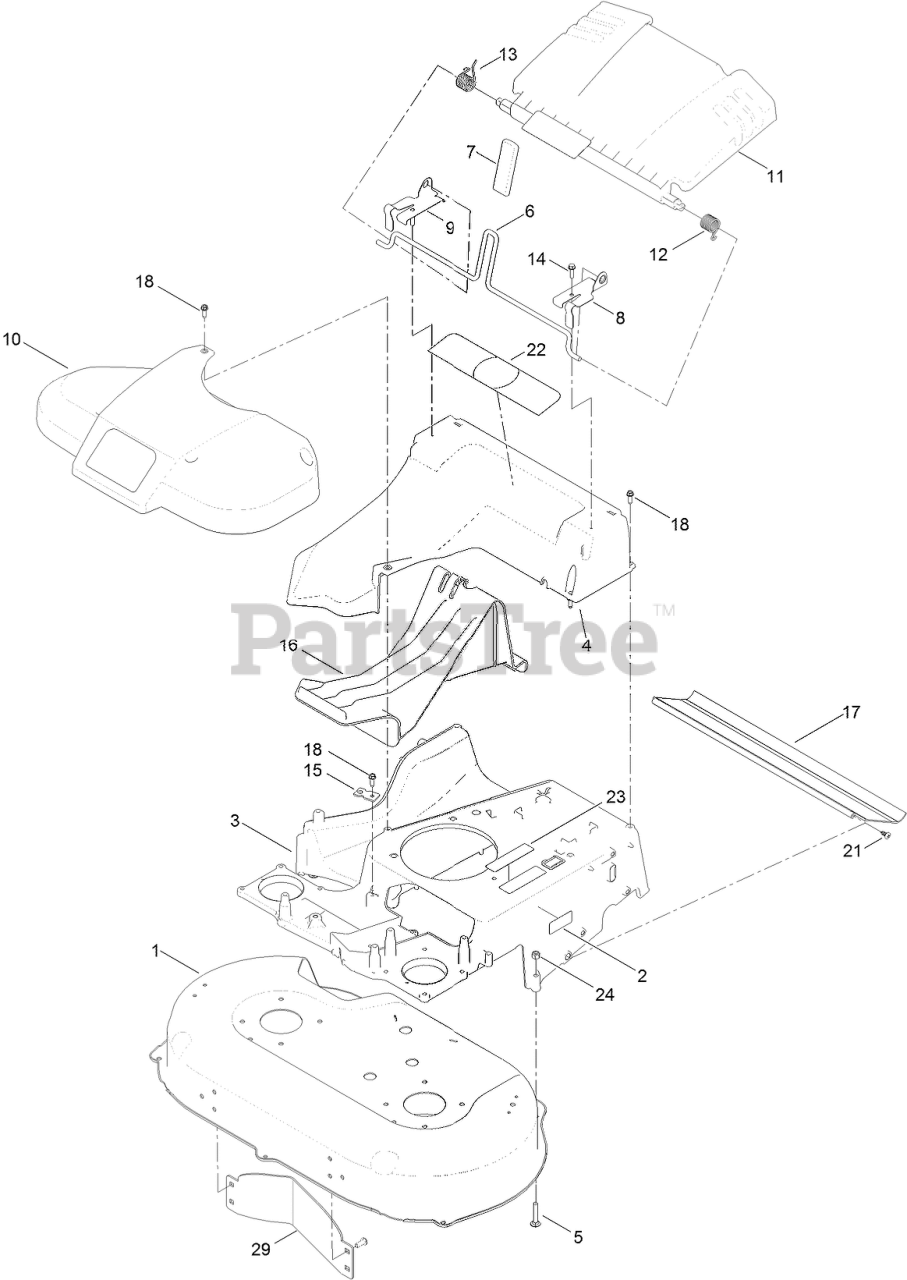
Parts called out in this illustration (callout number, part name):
1	HOUSING ASM
2	DECAL-LOCATION, SERVICE DEALER
4	CHUTE
5	SCREW-CARR
6	ROD-RELEASE, HANDLE
7	GRIP-LEVER
8	BRACKET-DOOR, LH
9	BRACKET-DOOR, RH
10	BELT COVER ASM
11	REAR DEFLECTOR ASM
12	SPRING-TORSION
13	SPRING-TORSION
14	SCREW-HWH
15	BRACKET-CABLE, TRACTION
16	PLUG-MULCH
17	SHIELD-TRAILING
18	SCREW-HWHTF
21	SCREW-PTH
22	DECAL-POSITION, HANDLE
23	DECAL-ARRESTER, SPARK
24	NUT-LOCK, NI
29	BAFFLE-CONTROL
